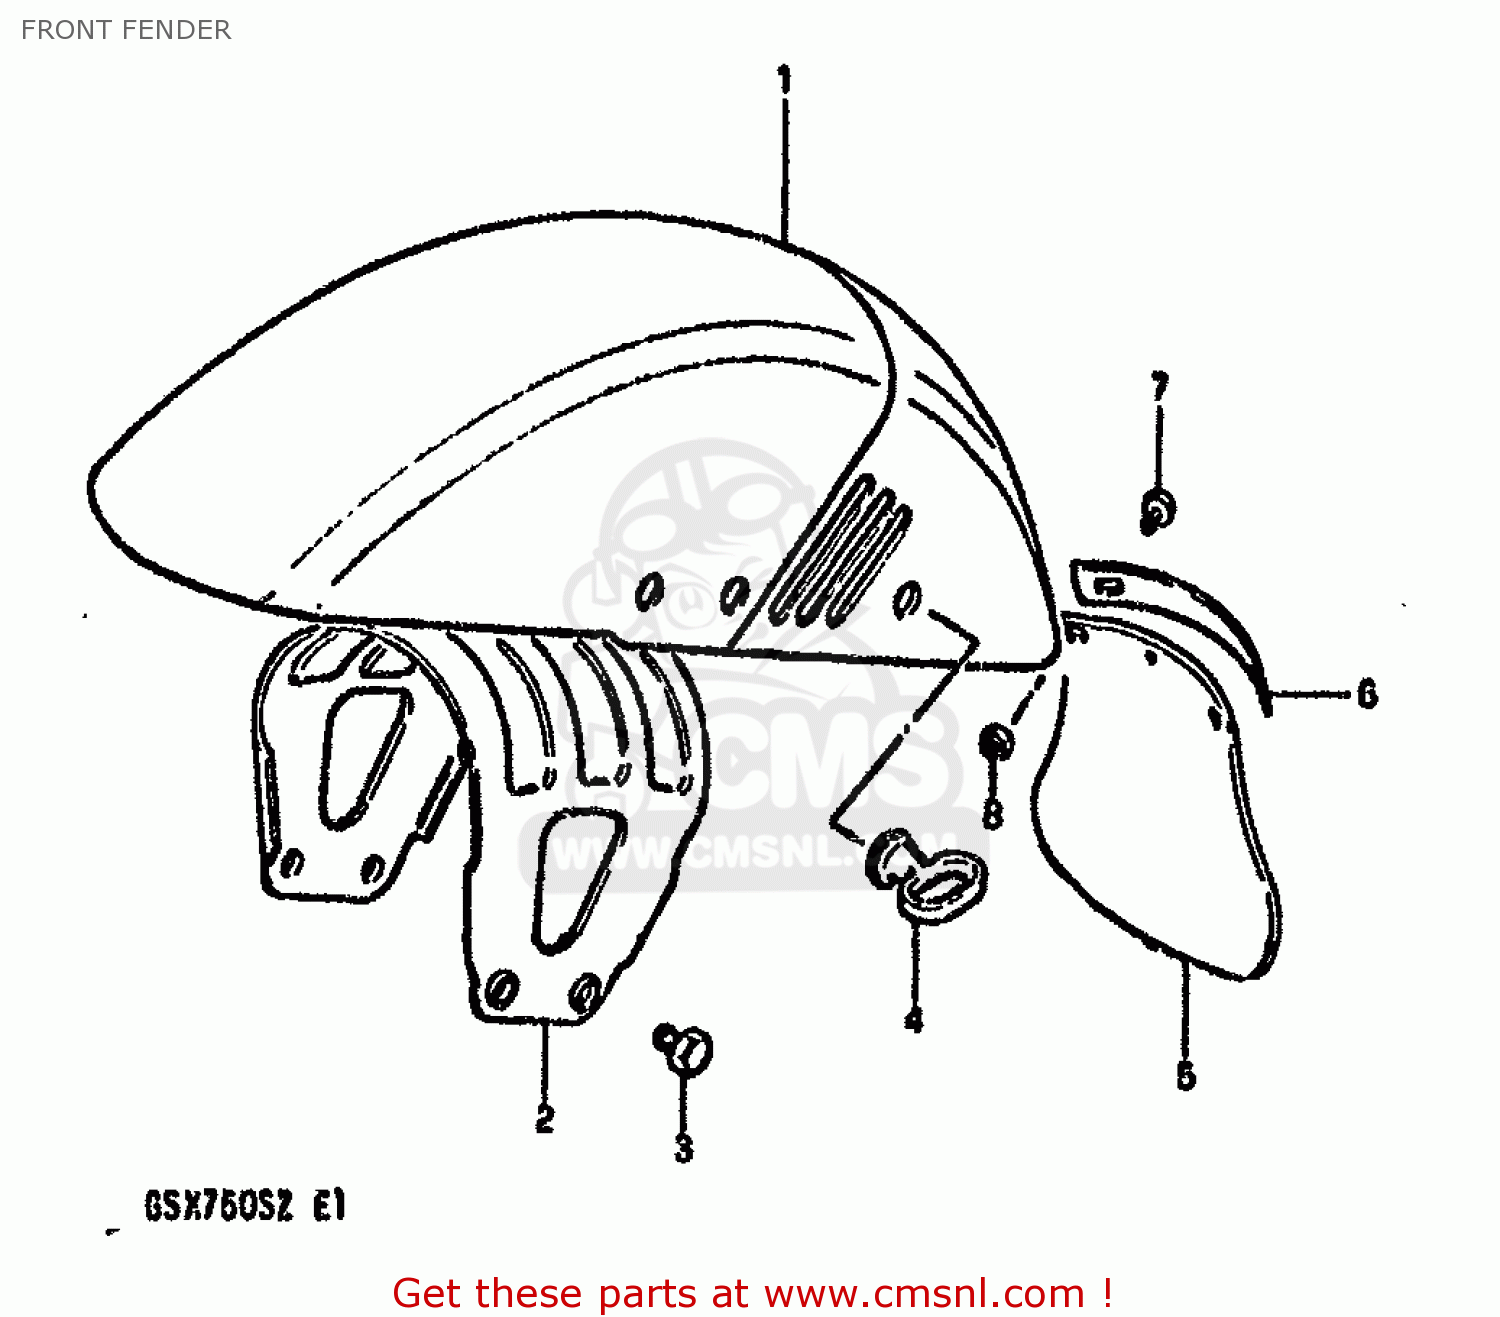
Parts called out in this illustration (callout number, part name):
1	FENDER,FRONT
2	BRACE,FRONT FENDER
3	BOLT 8X16
4	GUIDE,CABLE
5	FLAP,MUD
6	PLATE
7	SCREW
8	NUT 5MM
